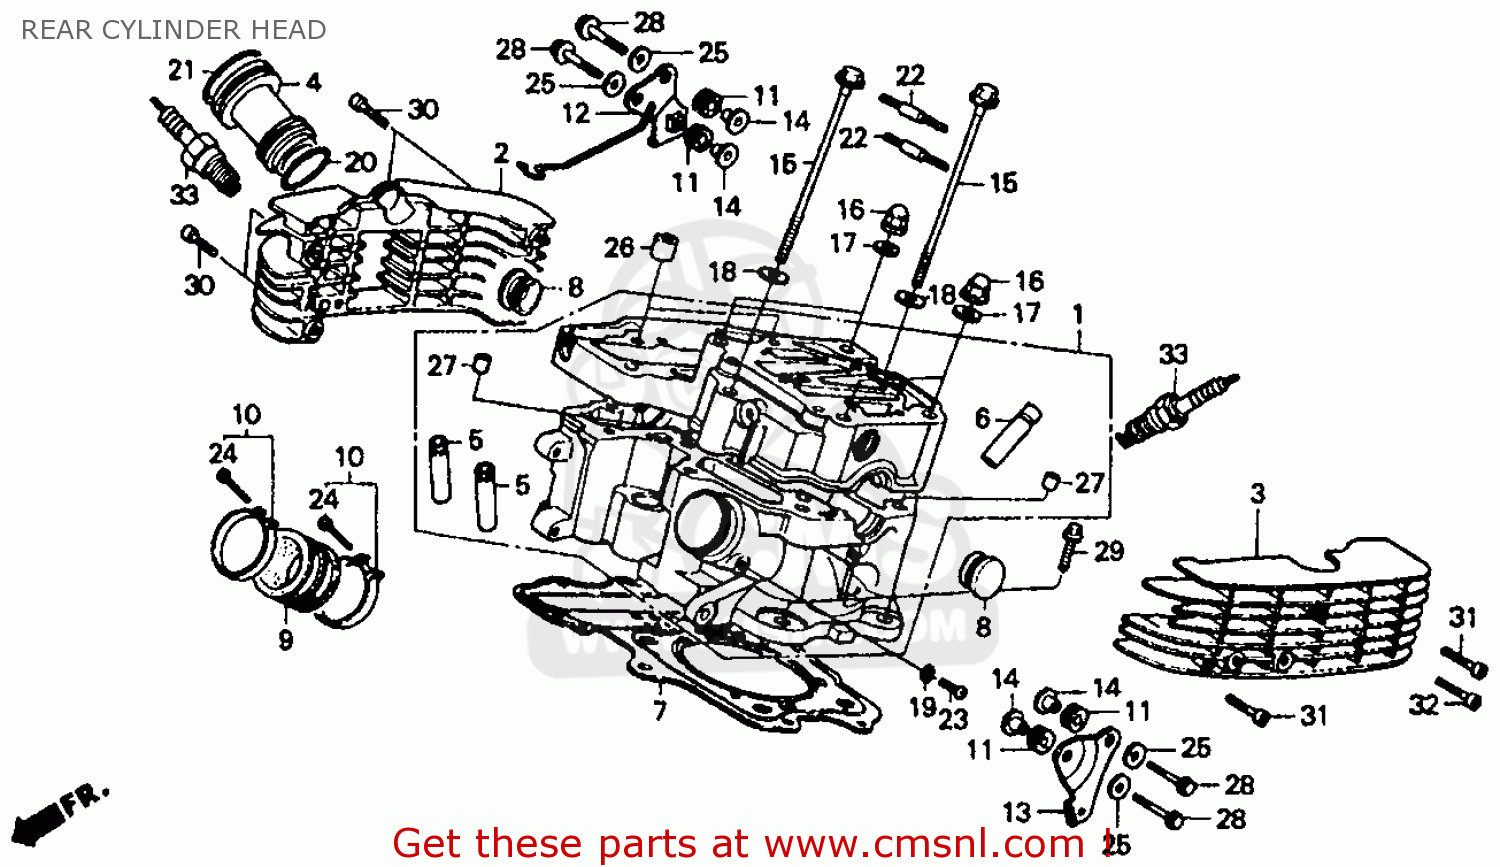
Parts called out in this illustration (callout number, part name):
1	HEAD ASSY,REAR CY
2	FIN A,REAR CYLIND
3	FIN B,REAR CYLIND
4	SLEEVE,PLUG
5	GUIDE,IN.VALVE
6	GUIDE,VALVE
7	GASKET CYLN HEAD (NAS)
8	PLUG CAM SHAFT
9	INSULATOR CARB
10	BAND,INSULATOR
11	GROMMET,HORN STAY
12	STAY,R.HORN
13	STAY,L.HORN
14	COLLAR TANK M/T
15	BOLT FLANGE,8X150
16	NUT,CAP,10MM
17	WASHER, SEALING, 10MM\t
18	WASH,SEALING,8MM
19	WASHER 5MM
20	O-RING,27.4X2.4
21	O-RING,35.3X2.4
22	BOLT,STUD,8X35
23	SCREW,CROSS 5X8
24	SCREW,PAN,5X25
25	WASHER,10MM
27	DOWEL,PIN,14X20
28	BOLT,FLANGE,6X25
29	BOLT,FLANGE,6X35
30	BOLT,SOCKET,6X20
31	BOLT SOCKET 6X35
32	SOCKET BOLT,6X45
33	SPARK PLUG(NGK)
